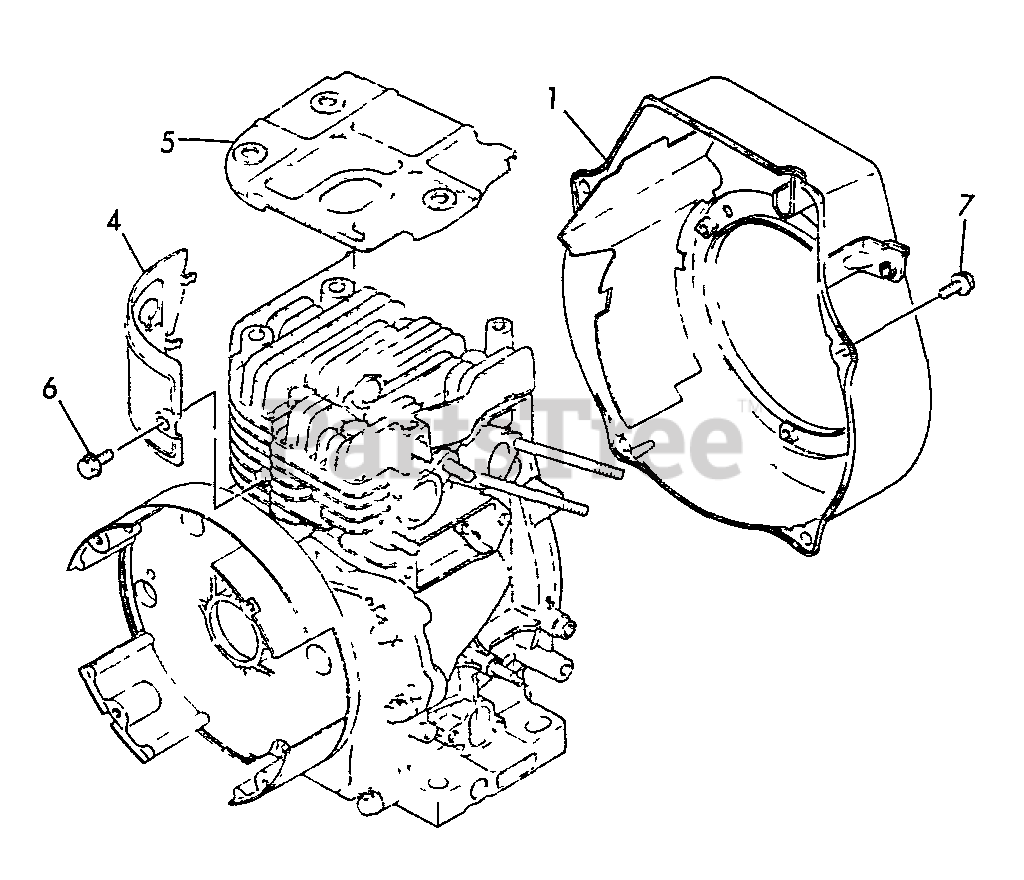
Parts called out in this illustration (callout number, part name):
1	CASE, FAN
4	PLATE
5	COVER, HEAD
6	BOLT - 6X8 -- PLATED
7	BOLT - 6X8 -- PLATED
